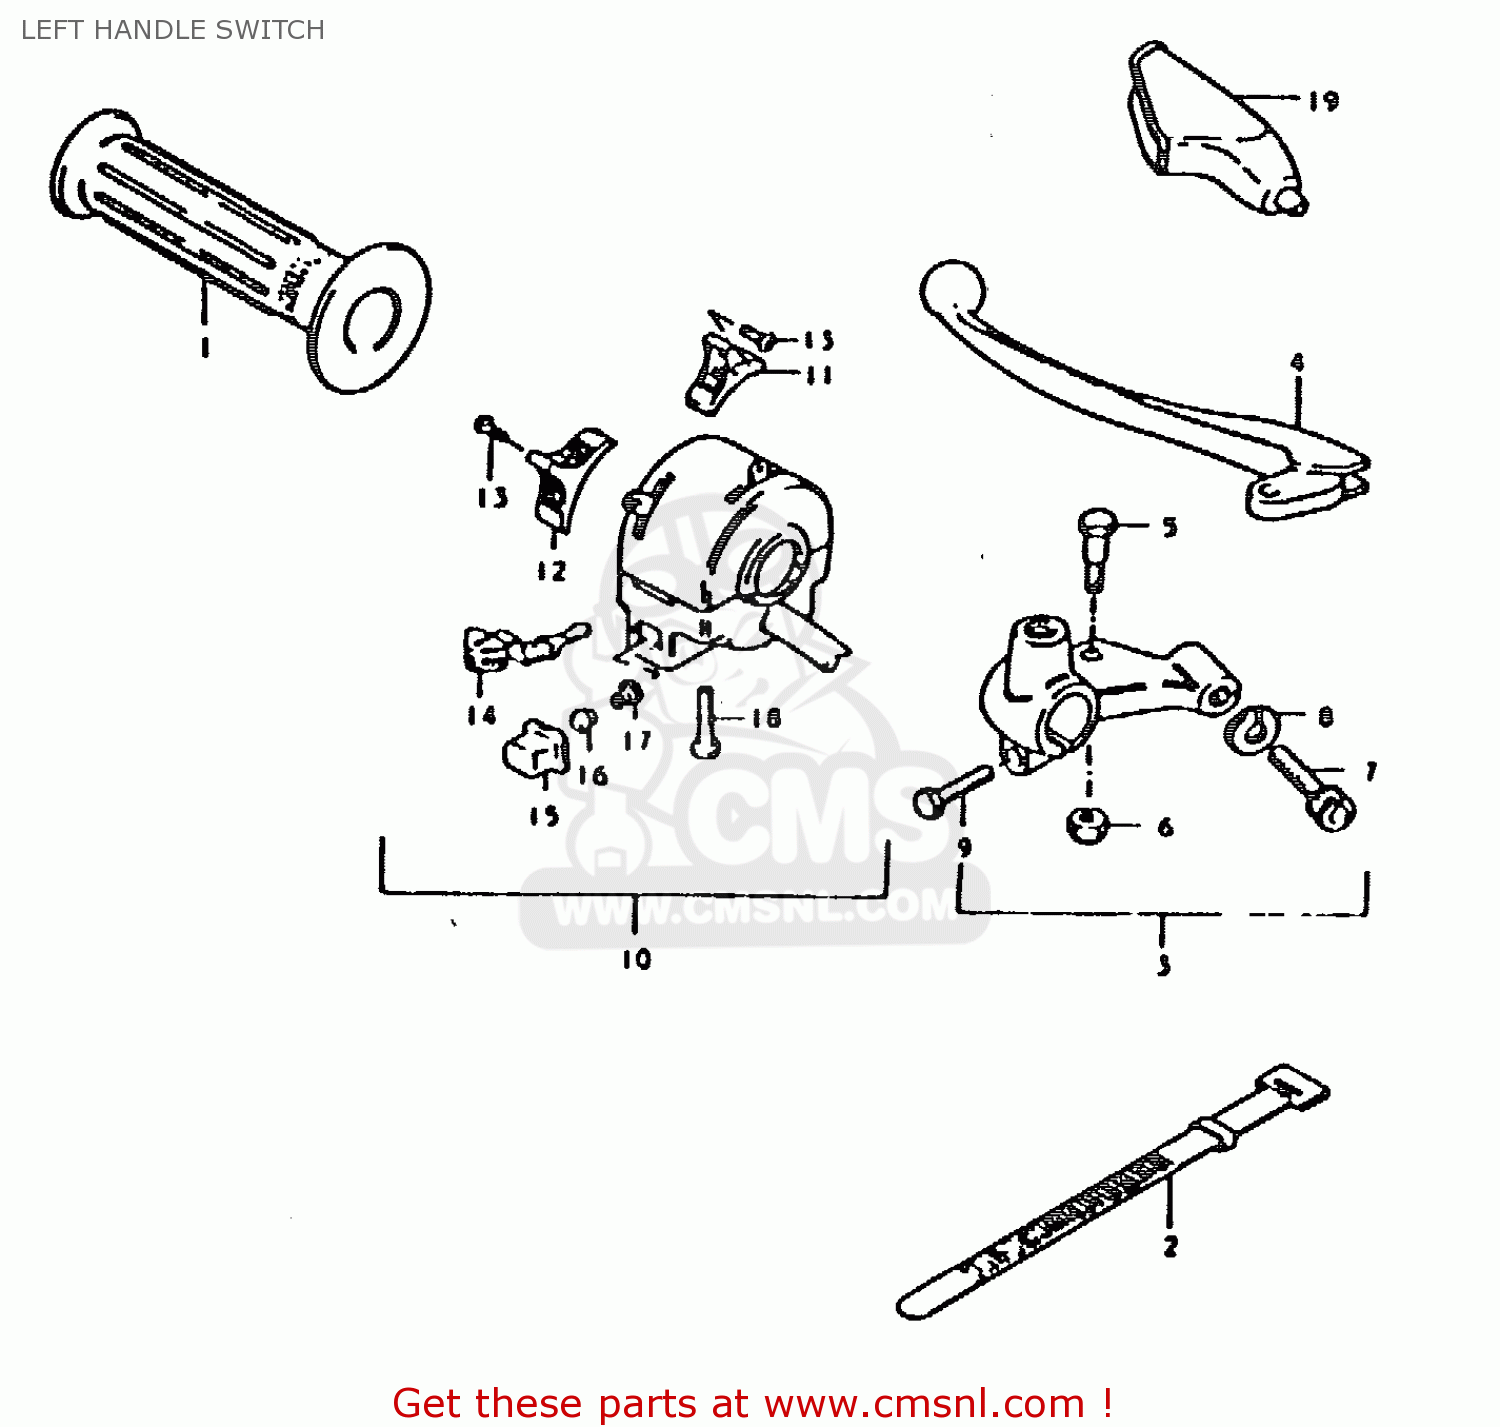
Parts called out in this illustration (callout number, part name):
1	GRIP,L
2	CLAMP(L:120)
3	LEVER ASSEMBLY,CLUTCH
4	LEVER,CLUTCH
5	BOLT,LEVER
6	NUT 6MM
7	ADJUSTER,CABLE
8	NUT,CABLE ADJUSTER
9	BOLT
10	SWITCH ASSY, HANDLE LH
11	KNOB,LIGHTING SWITCH
12	KNOB,DIMMER SWITCH
13	SCREW
14	KNOB,TURNSIGNAL
15	BUTTON,HORN
16	CONTACT
17	SPRING
18	SCREW
19	COVER,CLUTCH LEVER
